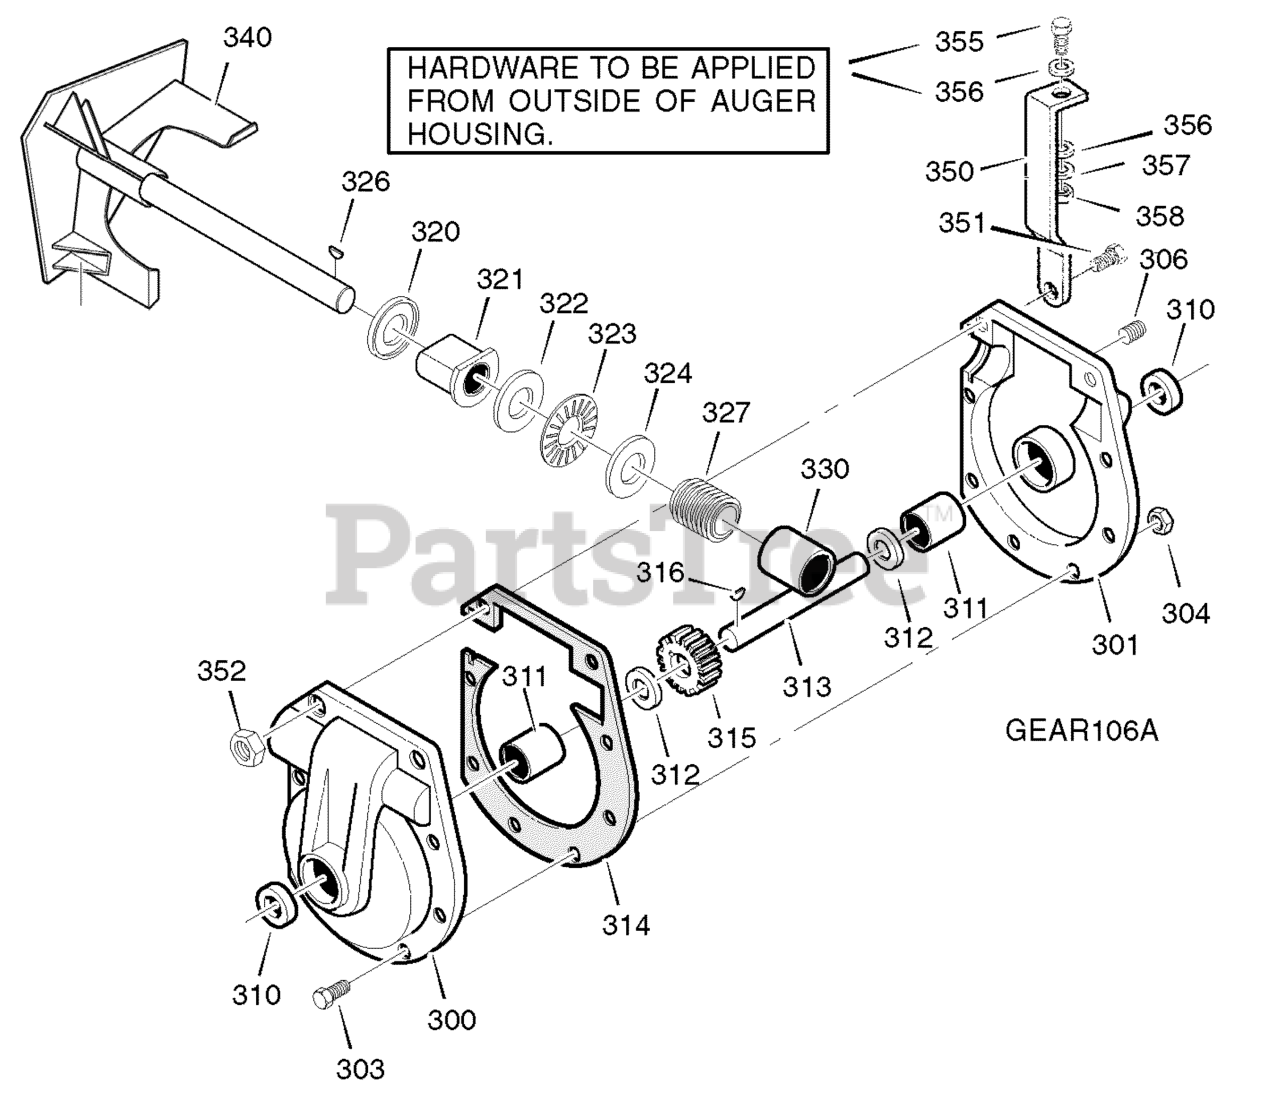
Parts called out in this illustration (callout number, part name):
300	CASE, GEAR, RH
301	CASE, GEAR, LH
303	SCREW, 5/16-24 x 1.00
304	NUT, 5/'16-24
305	SCREW, 5/16-24 x 1.50
306	PLUG, PIPE 0.25-18
310	SEAL, OIL
311	BEARING, SLEEVE
312	WASHER, FLAT
313	SHAFT, AUGER OUTPUT
314	GASKET, GEAR BOX
315	WORM GEAR
316	KEY, WOODRUFF #91
320	RING, QUAD 0.924 ID
321	BEARING, FLANGE
322	WASHER, FLAT
323	BEARING, ROLLER
324	WASHER, FLAT
326	KEY
327	GEAR, WORM
330	BEARING, SLEEVE
350	BRACE, GEAR BOX
351	SCREW, 5/16-24 x 1.75
352	NUT, HEX 5/16-24
355	SCREW, 5/16-18 x 1.25
356	WASHER, FLAT
357	WASHER, SPTLK
358	NUT, REGHEX 5/16-18
